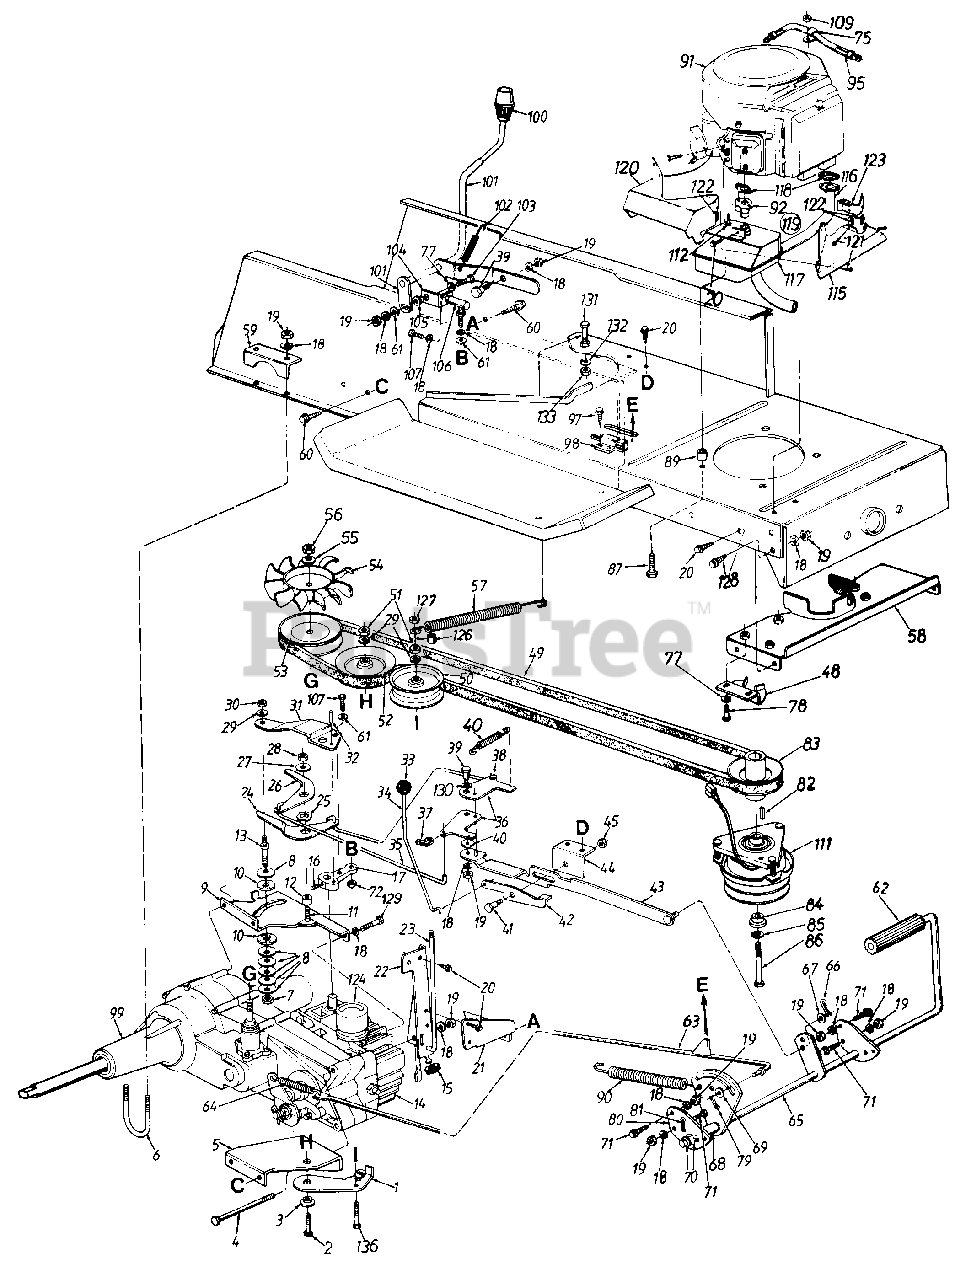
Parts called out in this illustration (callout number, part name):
1	Idler Bracket
2	Hex Bolt 3/8-16 x 2.0" Lg.
3	Shld. Spacer .625" I.D.
4	Hex Bolt 5/16-18 x 4.5" Lg. (Grade 5)
5	Idler Plate
6	U-Bolt 5/16-18 x 1.75" Lg.
7	Hex L-Nut 3/8-24 Thd.
8	Bell-Wash. .40" I.D. x 1.13"
9	Mounting Bracket
10	Friction Washer
11	Rib Neck Bolt 5/16-24 x .84" Lg.
12	Spacer
14	Hydrostatic Pump
15	Rubber Washer .33" I.D.
16	Set Screw
17	Pintle Shift Lever
18	L-Wash. 5/16" I.D.
19	Hex Nut 5/16-18 Thd.
20	Hex Wash. Hd. TT-Tap Scr. 1/4-20 x .5" Lg.
21	Reinforcement Plate
22	Transmission Torque Brkt.
23	Release Valve Rod
24	Reverse Arm
25	Spring Washer .625" I.D.
26	Forward Arm
27	Fl-Wash. .344" I.D. x 1.0"
28	Hex Cent. L-Nut 5/16-24 Thd.
29	L-Wash. 3/8" I.D.
30	Hex Nut 3/8-24 Thd.
31	Pintle Arm Ext. Plate
32	Roll Pin 1/4" Dia. x .75" Lg.
33	Ball Knob
34	Lock-Up Rod
35	Connection Rod
36	Balancer Bracket
37	Rod End Clevis Clips R.H.
38	Rod End Clevis Clips L.H.
39	Shld. Bolt .437" Dia. x .268"
40	Fl-Wash. .344" I.D. x 1.12"
41	Shld. Bolt .437" Dia. x .35"
42	Lock-Up Bracket
43	Neutral Return Brkt. Ass'y.
44	Bracket
45	Hex Cent. L-Nut 5/16-18 Thd.
50	Flat Idler
51	Hex Nut 3/8-16 Thd.
52	Idler Pulley 4.0" O.D.
53	Transmission Pulley
54	Hydro Fan
55	Bell-Wash. .56" I.D. x 1.125"
56	Hex Jam Nut 9/16-18 Thd.
57	Extension Spring
58	Belt Guard Brkt. Ass'y.
59	Bracket
60	Hex Wash. Hd. B-Tap Scr. 5/16-18 x .5" Lg.
61	Flat Tooth Washer 5/16" I.D.
62	Foot Pad
63	Brake Rod Ass'y.
64	Ext. Spring 3.67" Lg.
65	Clutch Brake Pedal Ass'y.
66	Intern. Cotter Pin 5/16" Dia.
67	Fl-Wash. .385" I.D. x .62"
68	Spacer.63" I.D.
69	Fl-Wash. .385" I.D. x .62"
70	Fl-Wash. .635" I.D. x 1.0"
71	Hex Wash. TT-Tap Scr. 5/16-18 x 7/8" Lg.
72	Part Specification Not Listed
75	Clamp
77	Bell-Wash. .345" I.D. x .88"
78	Hex Bolt 5/16-18 x .75" Lg. (Grade 5)
79	Cotter 3/32" Dia. x .75" Lg.
80	Pedal Brkt.
81	Cotter Pin 3/32" Dia. x 1.0" Lg.
82	Sq.-Key 1/4" x 1.5"
83	Engine Pulley Ass'y.
84	Shld. Spacer .445" I.D. x 1.38"
85	L-Wash. 7/16" I.D. (H.D.)
86	Hex Bolt 7/16-20 x 5.0" Lg.
87	Hex Wash. Hd. AB-Tap Scr. 3/8-16 Thd.
89	Spacer 5/16" I.D.
90	Extension Spring 6.11" Lg.
91	Engine
92	Inlet Tube Ass'y.
95	Hydraulic Hose 13" Lg.
97	Hex Wash. Hd. B-Tap Scr. #10 x 3/8" Lg.
98	Safety Switch (Clutch)
99	Transaxle
100	Shift Knob
101	Speed Selector Lever Ass'y.
102	Ext. Spring 2.75" Lg.
103	Hex Bolt 5/16-18 x 1.25" Lg.
104	Connection Brkt.
105	Shoulder Nut
106	Ball Joint 5/16-24 Thd.
107	Hex Bolt 5/16-24 x .75" Lg.
109	Hex Jam Nut 3/8-16 Thd.
111	Electric Clutch
112	Hex Bolt w/Washer
115	Muffler Heat Shield Front
116	Formed Tube Ass'y.
117	Exhaust Muffler Sub Ass'y.
118	Gasket
119	Muffler Ass'y. Comp.
120	Muffler Heat Shield
121	Hex Wash. Tap Scr. #10 x .5" Lg.
122	Speed Nut #10-24 Thd.
123	Front Heat Shield Ext.
124	Reservoir
126	Spacer .375" I.D. x .503"
127	Hex Jam Nut 3/8-16 Thd.
128	Hex Wash. TT-Tap Scr. 5/16-18 x.62" Lg.
129	Hex Bolt 5/16-18 x 43/4" Lg.
130	Spr.-Wash. .445" I.D. x .75" O.D.
131	Hex Bolt 1/4-20 x 1.25" Lg.
132	L-Wash. 1/4" I.D.
133	Hex Nut 1/4-20 Thd.
136	Hex Bolt 3/8-16 x 2.5" Lg.
